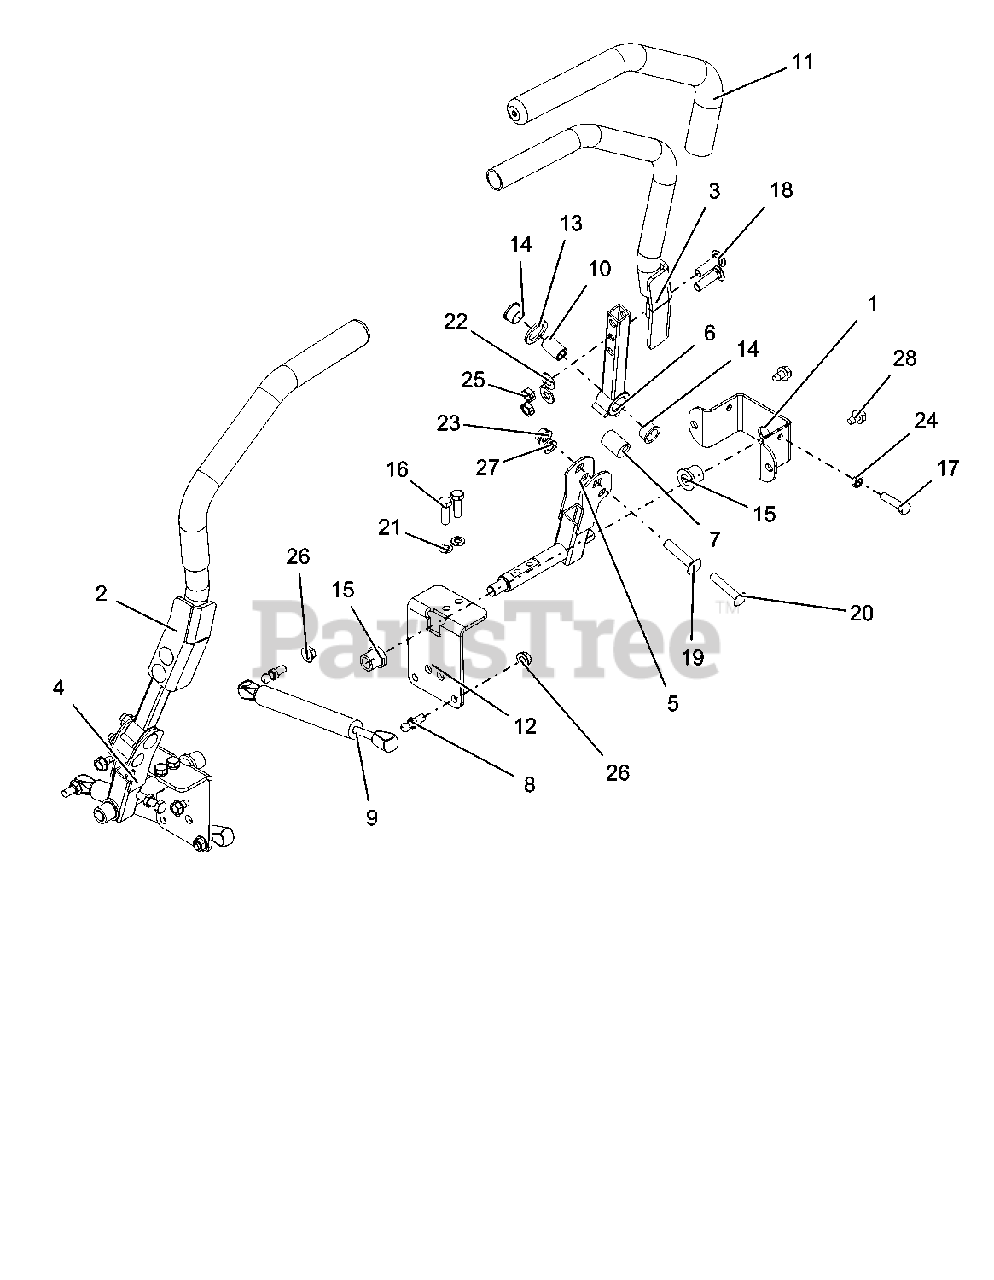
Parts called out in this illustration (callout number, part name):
1	BRKT, STEERING PIVOT (BLACK)
2	WLDMT, STEERING HANDLE RH
3	WLDMT, STEERING HANDLE LH
4	WLDMT, LOWER STEERING ARM
5	WLDMT, LOWER STEERING ARM-LH
6	WLDMT, UPPER CONTROL ARM (BLACK)
7	BSHG, SPCR .328X.750X1.01 PM
8	STUD-BALL
10	SPCR, .375X.625X.970
11	GRIP, HANDLEBAR 15" FOAM
12	BRKT, STEERING
13	WSHR, FRICTION .875X1.25X.10
14	BSHG, .625X.75X.450X.875
15	BSHG, FLANGE .515 X .750 X .745 X 1.00 NYLON
16	BLT-HEX .31-18X1.00 GR8 YWZC
17	BLT-HEX .31-18X1.25 GR5 YWZC
18	BLT-RHDSSQNK .38-16X1.25 G5YZ
19	BLT-RHDSSQNK .38-16X1.75 G5YZ
20	BLT-RDHDSQSHNK .31-18X1.75 YWZC
21	WSHR-LK .31X.078 REG YWZC
22	WSHR-FL-STL.406X.812X.065 YWZ
23	NUT, LK-CTR-FLG .38-16 YWZC
24	NUT, JAM .312-18 YWZC
25	NUT-LK-CTR-JAM .375-16 YWZC
26	NUT, LK-TOP-FLG .312-18 YWZC
27	NUT-LK-NYL-FLG .31-18 YWZC
28	SCR-TAP .31-18X.50 HWH TR YWZ
